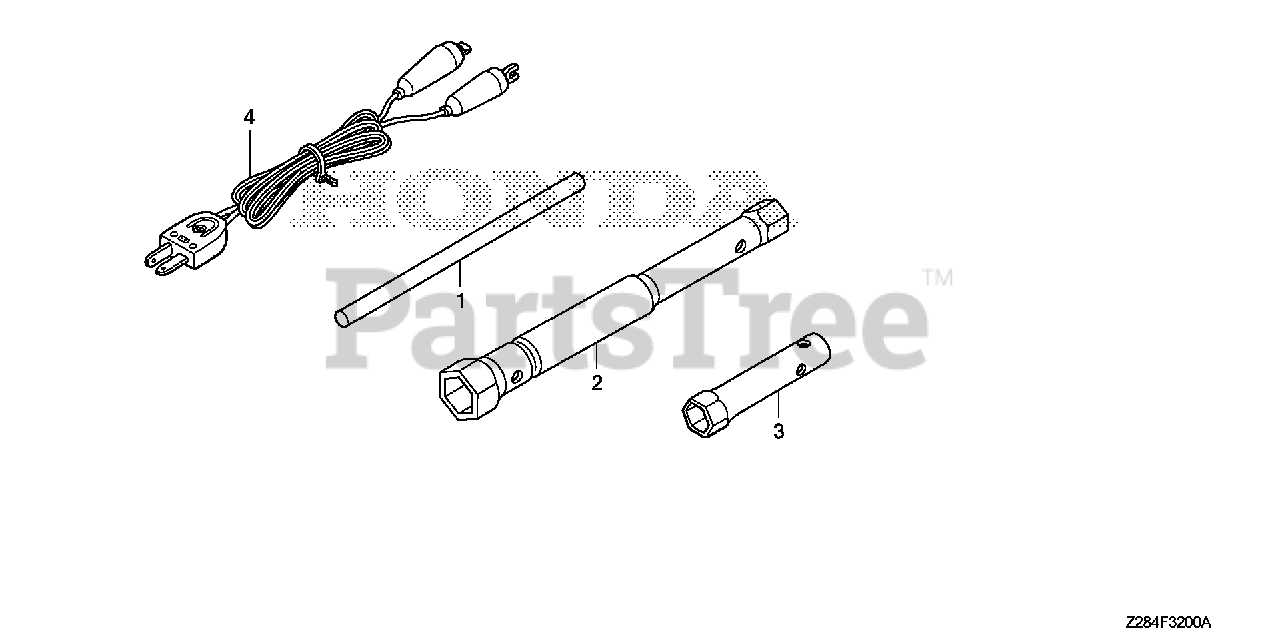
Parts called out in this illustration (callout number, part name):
1	BAR, PLUG WRENCH
2	WRENCH, BOX (P21X10)
3	WRENCH, BOX (10MM) (NOT AVAILABLE)
4	WIRE ASSY., CHARGE (2M)
4	WIRE ASSY., CHARGE
